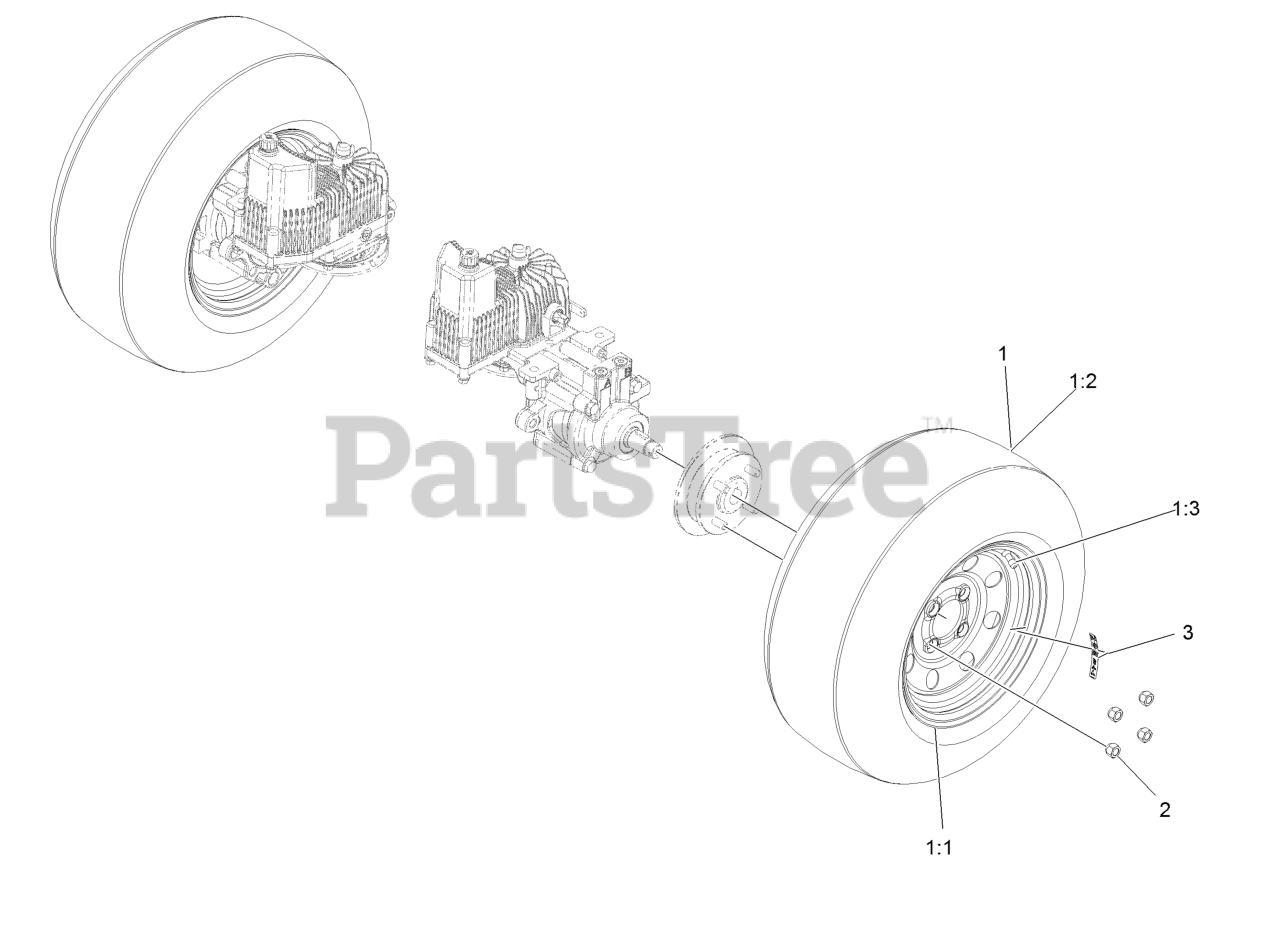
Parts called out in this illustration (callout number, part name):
1	Wheel And Tire ASM
1:1	ASM, Rim
1:2	Tire-Drive, 23X9.5-12
1:3	Stem-Valve
2	Nut-Lug 1/2-20
3	Decal-Torque, Wheel Hub Lug
